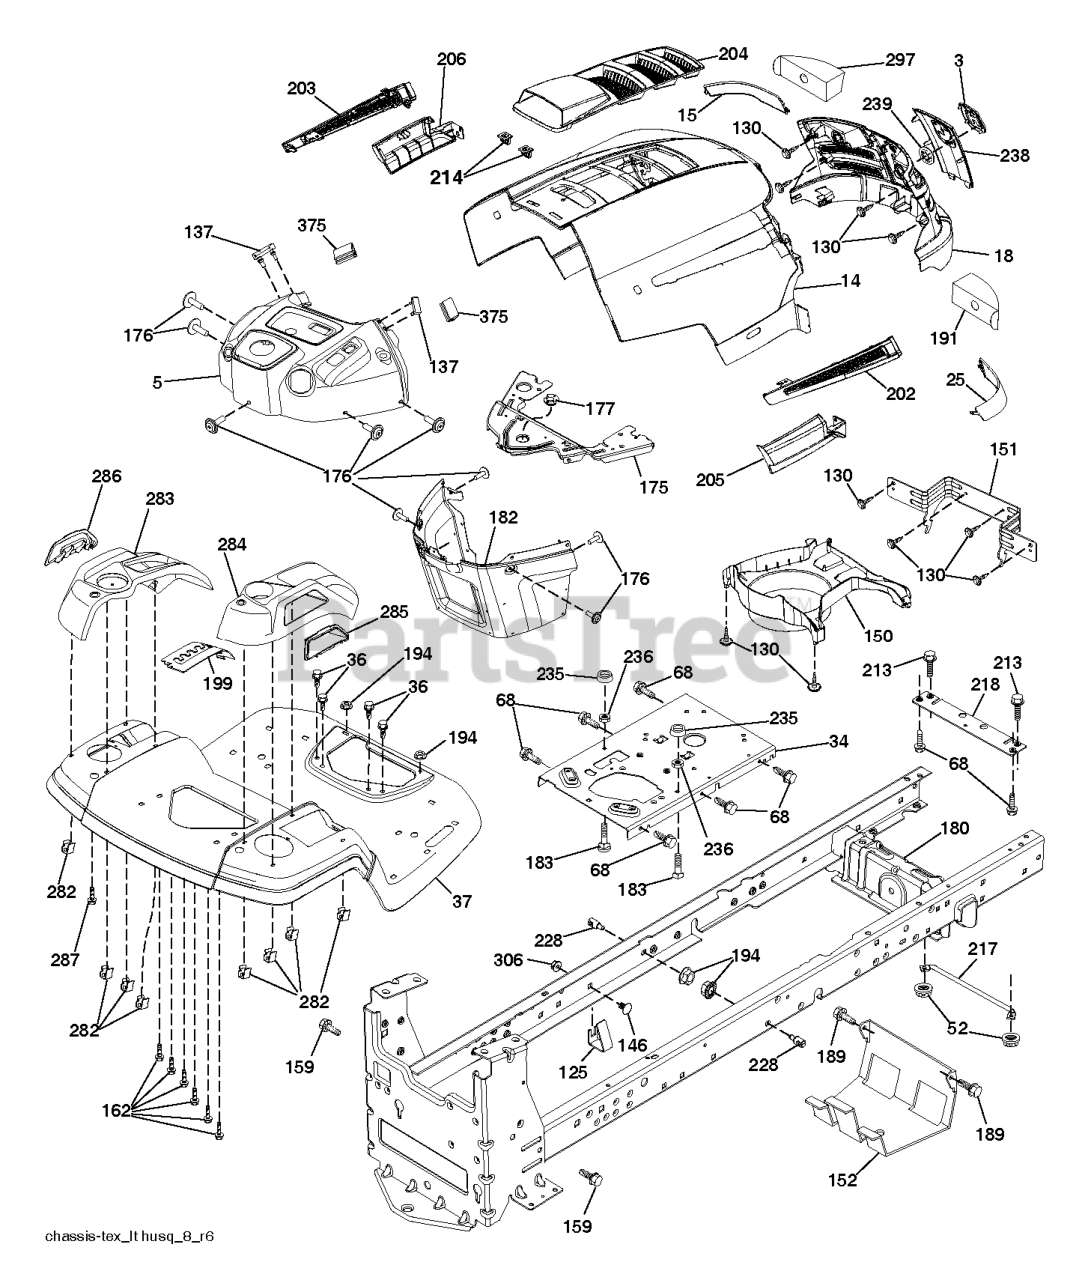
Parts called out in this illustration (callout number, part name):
3	LOGO.HUSQ.GT.LT.CROWN.H
5	SUBASM.DASH.UPPER.HLT.498
14	HOOD.HUSQVARNA.LT.ORANGE
15	LENS.HUSQVARNA LT.RH
18	GRILLE.SVC.HUSQVARNA.GREY
25	LENS.HUSQVARNA LT.RH
34	PLATE.ENGINE.WELDED.CHASSIS
36	SCREW 5/16"
37	FENDER.TLT.FS.W/CUPHLD.ORANGE
52	LOCKNUT
68	SCR 5/16-18 X 1/2 SELFTAP ZN
125	CLIP.FUEL.LINE
130	SCREW.#10 X 0.750.BOS
137	BUMPER DASH
146	BOLT.RDHD.SHT.SQNK.3/8-16X5/8
151	BRACKET PIVOT
152	SHIELD.BROWNING.W/TEX
159	SCREW, 3/8-16X3/4
162	SCREW.HI-LO.CONSOLE
175	CROSSMEMBER
176	SCREW.#10-24X5/8.RN.QU
177	BUSHING STEERING
180	CHASSIS
182	DASH.LOWER.PREDATOR LT
183	BOLT.5/16-18X1-1/4 FULL THD
189	SCREW
191	INSERT.REFLECTIVE.RH.
194	NUT LOCK HEX FLANGE 5/16-18
199	PLATE.DECK.LIFT.HUSQ.LT
202	VENT.SIDE.HUSQVARNA.LT.RT
203	VENT.SIDE.HUSQVARNA.LT.LFT
204	SUBASM.TOP.VENT.HUSQ.LT
205	SKIRT.SIDE.HUSQVARNA.LT.RT
206	SKIRT.SIDE.HUSQVARNA.LT.LEFT
213	HCS 5/16C X 3/4
214	CLIP.RETAINER.TINNER.
217	ROD.PIVOT.HOOD
218	X-PIECE.HOOD.STOP.NON/
228	STUD.FASTNER.W/ANTI-ROTATE
235	SPACER FENDER
236	NUT.CENTERLOCK.5/16-
238	TRIM.HUSQ LT.668
282	CLIP.RETAINER.CONSOLE.LT.HUSQ
283	CONSOLE.ASM.LFT.RSF.HUSQ.LT
284	CONCOLE.CNTRL.PDL.HUSQ.LT.498
285	CONSOLE INSERT RH
286	CONSOLE.INSRT.LH.HUSQ.LT.BLACK
287	SCREW 1/4X20
297	INSERT REFLECTIVE
306	NUT LOCK FLG 3/8-16 UNC
375	BUMPER CLIP-ON. DASH 1"
